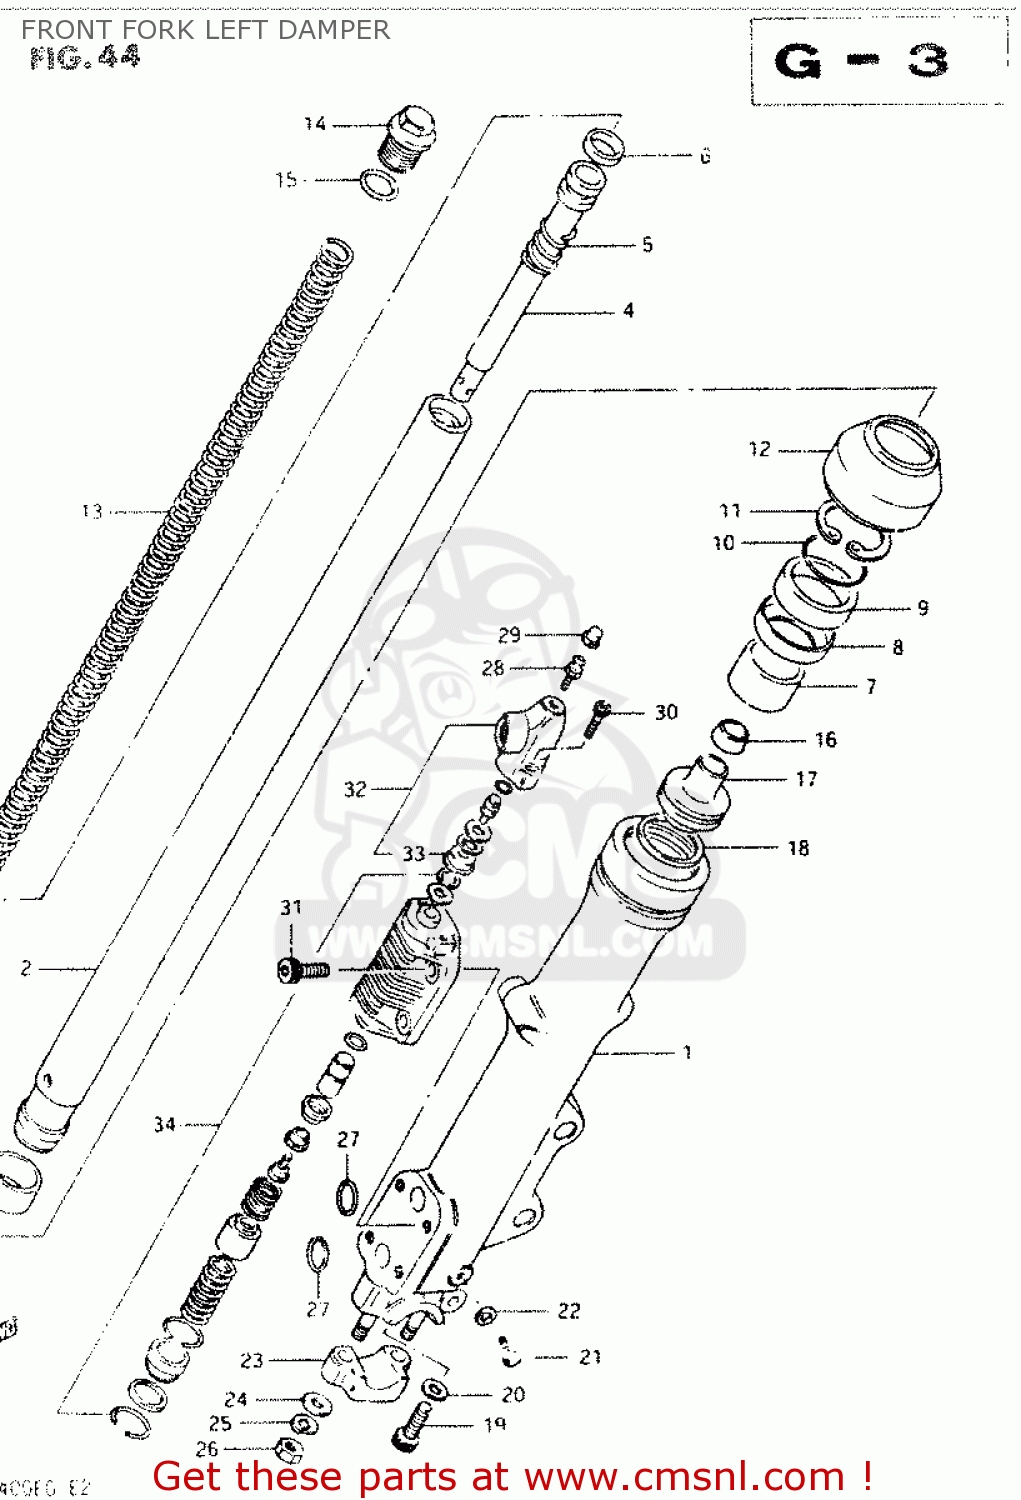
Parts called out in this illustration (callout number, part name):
1	OUTER TUBE LH
2	INNER TUBE,L
3	BUSH
4	CYLINDER, LH
5	SPRING,REBOUND
6	RING,PISTON
7	BUSH,GUIDE
8	SPACER,OIL SEAL
9	OIL SEAL,FRONT FORK
10	RING,BACKUP
11	RING,OIL SEAL STOPPER
12	DUST SEAL
13	SPRING,FR.FORK
14	BOLT
15	O RING
16	VALVE,OIL LOCK PIEACE
17	PIECE,OIL LOCK
18	RING, PISTON
19	BOLT(8X27)
20	GASKET (NAS)
21	BOLT
22	GASKET,DRAIN,PLUG (NAS)
23	HOLDER,AXLE
24	WASHER
25	LOCK WASHER
26	NUT
27	O RING,FR FORK
28	BREATHER
29	CAP
30	BOLT
31	BOLT
32	MODULATOR PARTS SET,FRONT
33	SEPARATOR,FRONT FORK MODULATOR
34	MODULATOR VALVE SET
